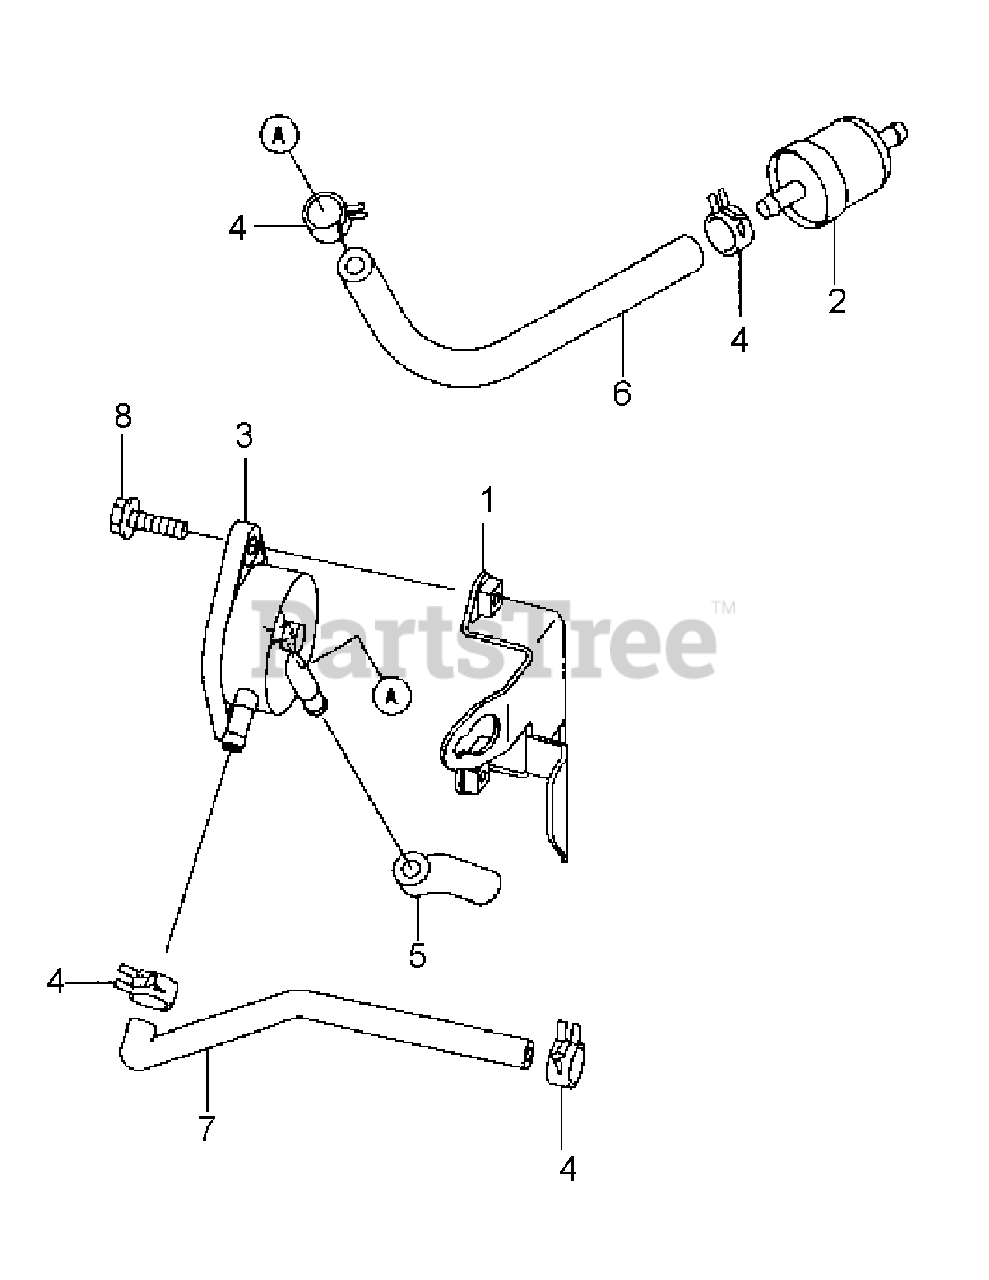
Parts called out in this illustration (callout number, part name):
2	FUEL FILTER
3	FUEL PUMP
4	CLAMP
6	TUBE, 6.35x12.7x160
8	FLANGED BOLT
